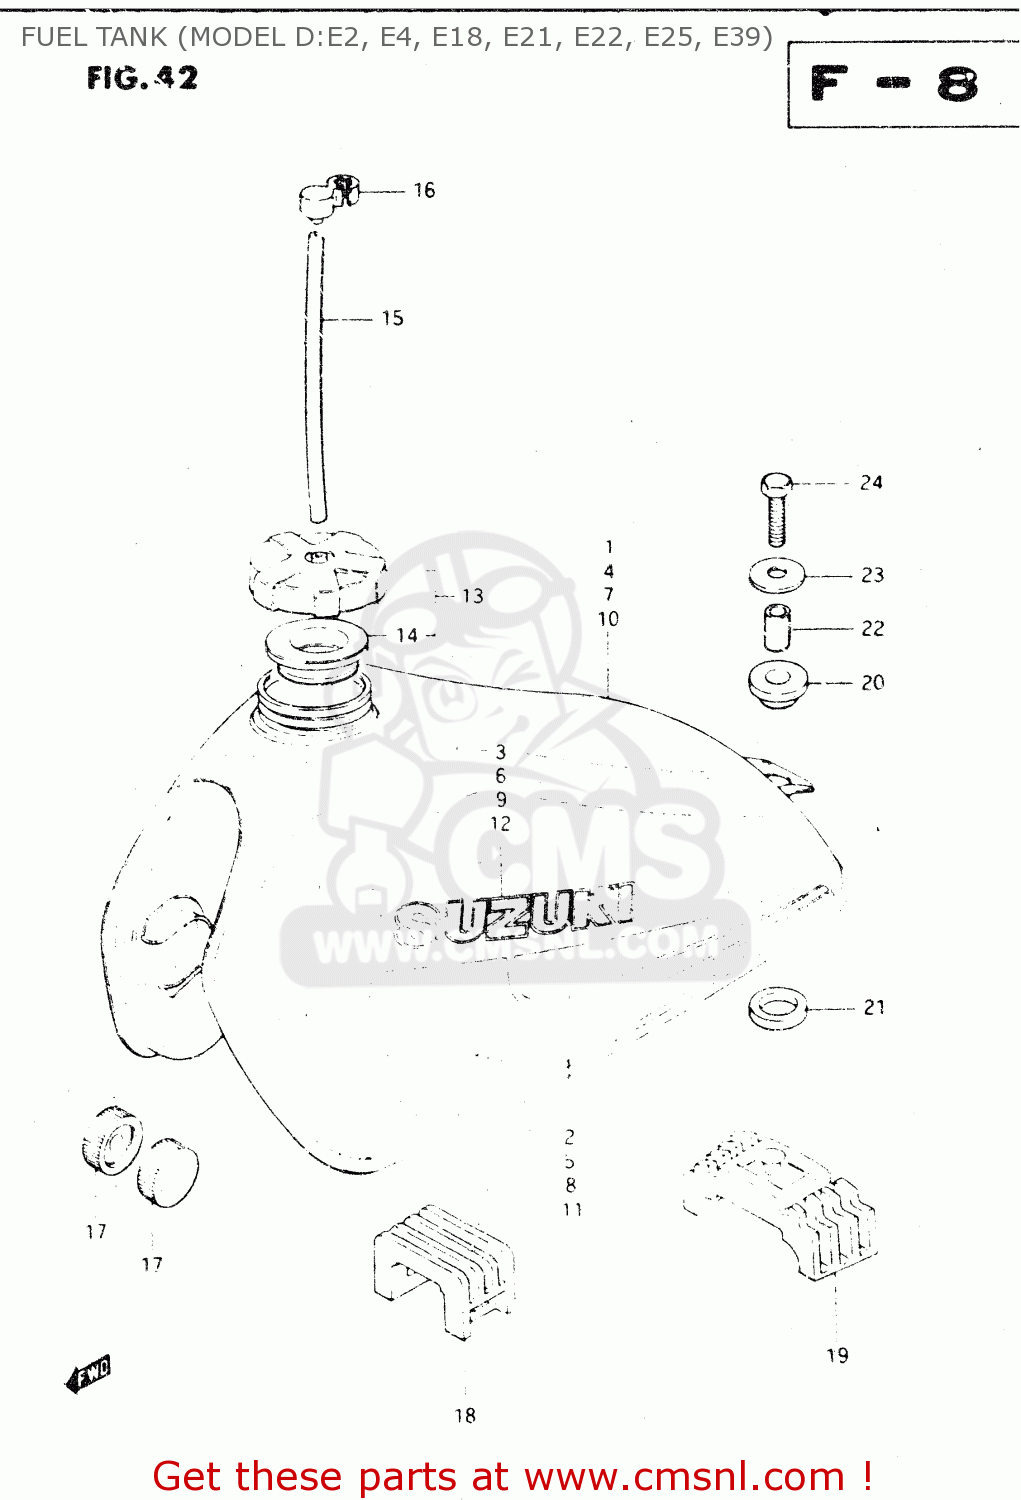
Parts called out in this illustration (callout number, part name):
1	TANK ASSY, FUEL (BLACK)
2	TAPE SET, FUEL TANK
3	EMBLEM,FUEL TANK(WHITE)
4	TANK ASSY, FUEL (BLUE)
5	TAPE SET, FUEL TANK
6	EMBLEM,FUEL TANK(WHITE)
7	TANK ASSY, FUEL (RED)
8	TAPE SET, FUEL TANK
9	EMBLEM,FUEL TANK(WHITE)
10	TANK ASSEMBLY,FUEL
11	TAPE SET,FUEL TANK
12	EMBLEM
13	CAP SET,FUEL TANK
14	GASKET (NAS)
15	HOSE
16	CLAMP,FUEL TANK BREATHER HOSE
17	CUSHION
18	CUSHION,TANK UPR FR
19	CUSHION,FUEL TANK,REAR
20	CUSHION
21	CUSHION
22	SPACER(8.5X12X19)
23	WASHER (8.5X29X1.6)
24	BOLT (8X30)
